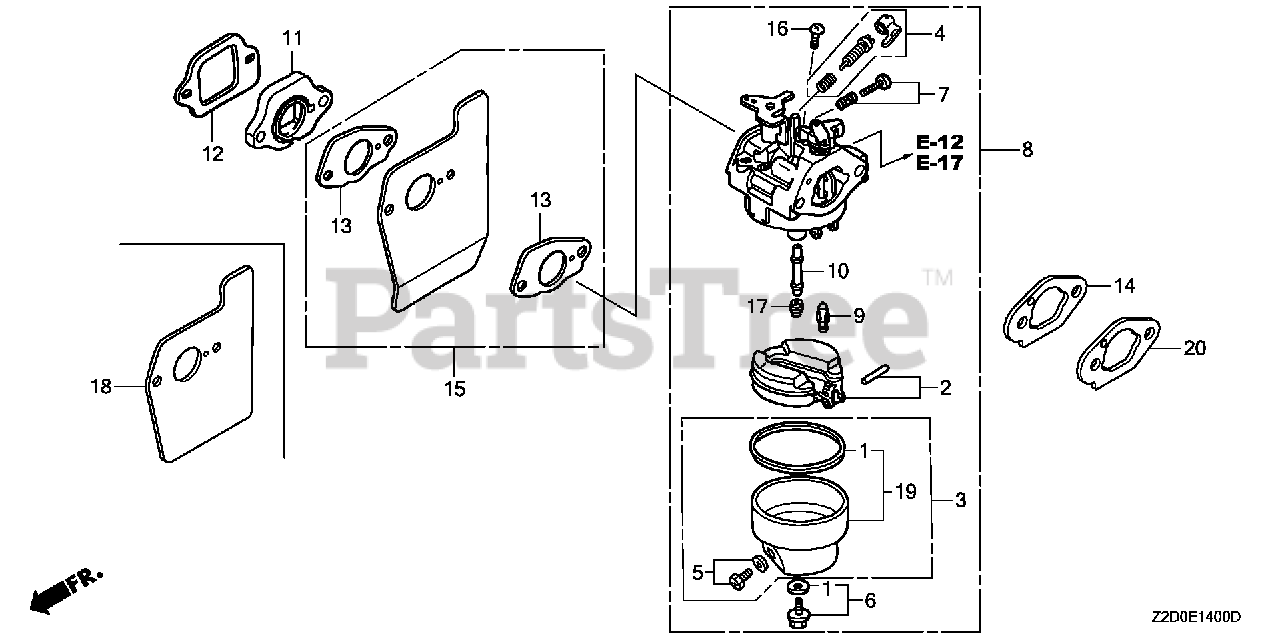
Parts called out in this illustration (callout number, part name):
1	GASKET SET
3	CHAMBER SET, FLOAT (CARBURETOR NO.)
4	SCREW SET (CARBURETOR NO.)
5	SCREW SET, DRAIN (CARBURETOR NO.)
6	SCREW SET
7	SCREW SET (THROTTLE STOP) (CARBURETOR NO.)
8	CARBURETOR ASSY. (BB65G C)
9	VALVE, FLOAT (CARBURETOR NO.)
10	NOZZLE, MAIN
11	INSULATOR, CARBURETOR
12	GASKET, INSULATOR
13	GASKET, CARBURETOR
14	GASKET, CARBURETOR
15	GUIDE, AIR
16	SCREW, PAN (5X6)
17	JET, MAIN (#62)
17	JET, MAIN (#65)
17	JET, MAIN (#68)
